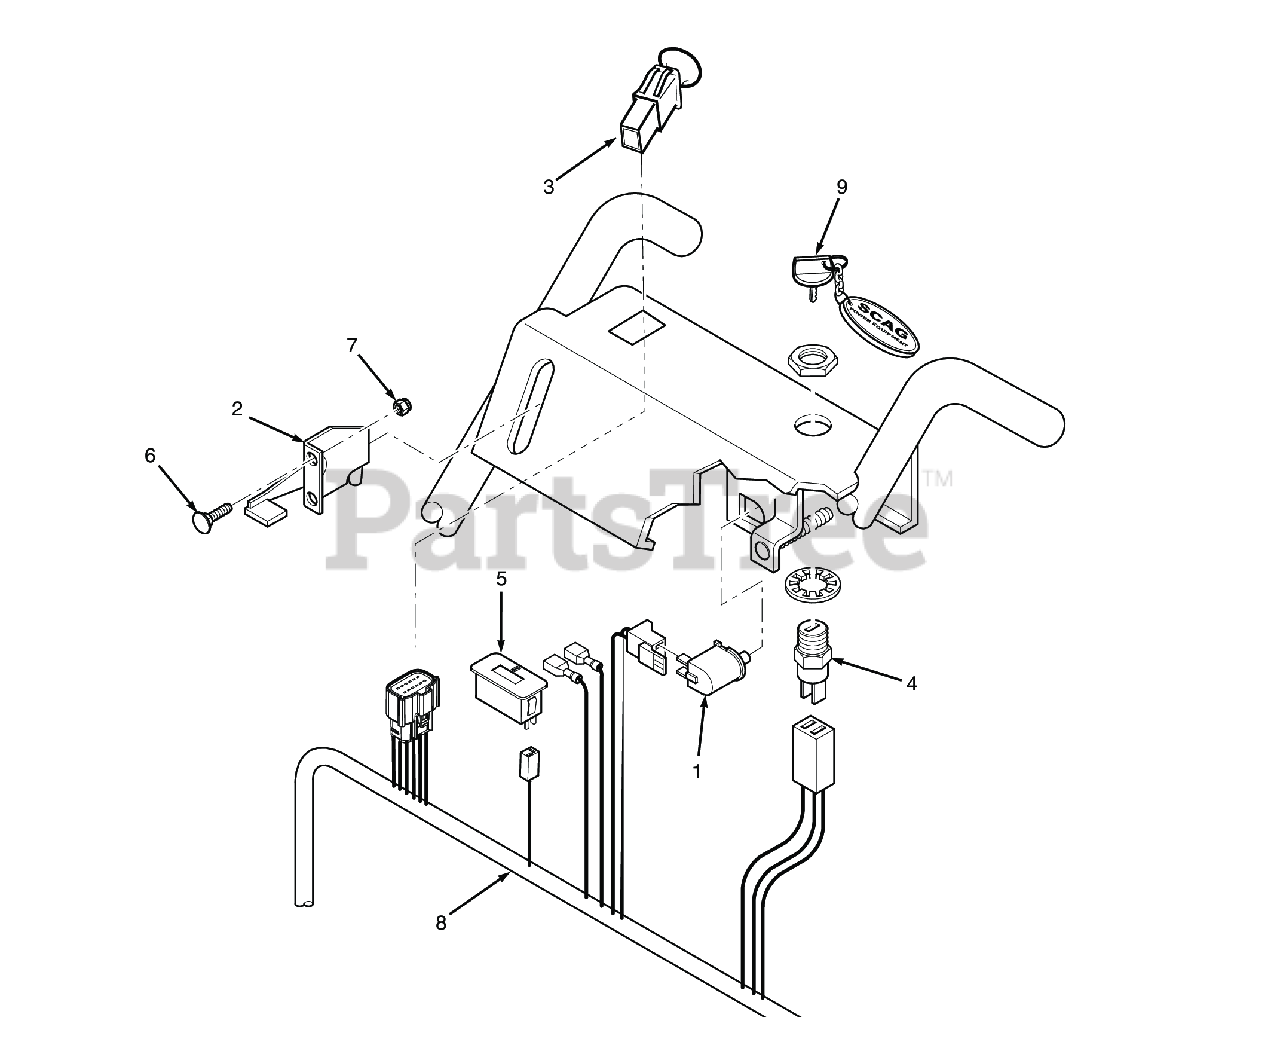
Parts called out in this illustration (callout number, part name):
1	SWITCH, NEUTRAL INTERLOCK
2	Throttle Control (15KA & 17KA)
3	Switch, PTO - 10 Amp
4	KEY SWITCH, MANUAL SRT.(INCL. HWD)
5	Hour Meter, Inductive
6	Bolt, Carriage #10-24 x 1/2"
7	Nut, Elastic Stop #10-24
8	Handle Wire Harness, Manual Start
9	Key, Assembly w/Fob
9	Key w/Shroud Only
NS	Clamp, Cable 1/2" I.D.
